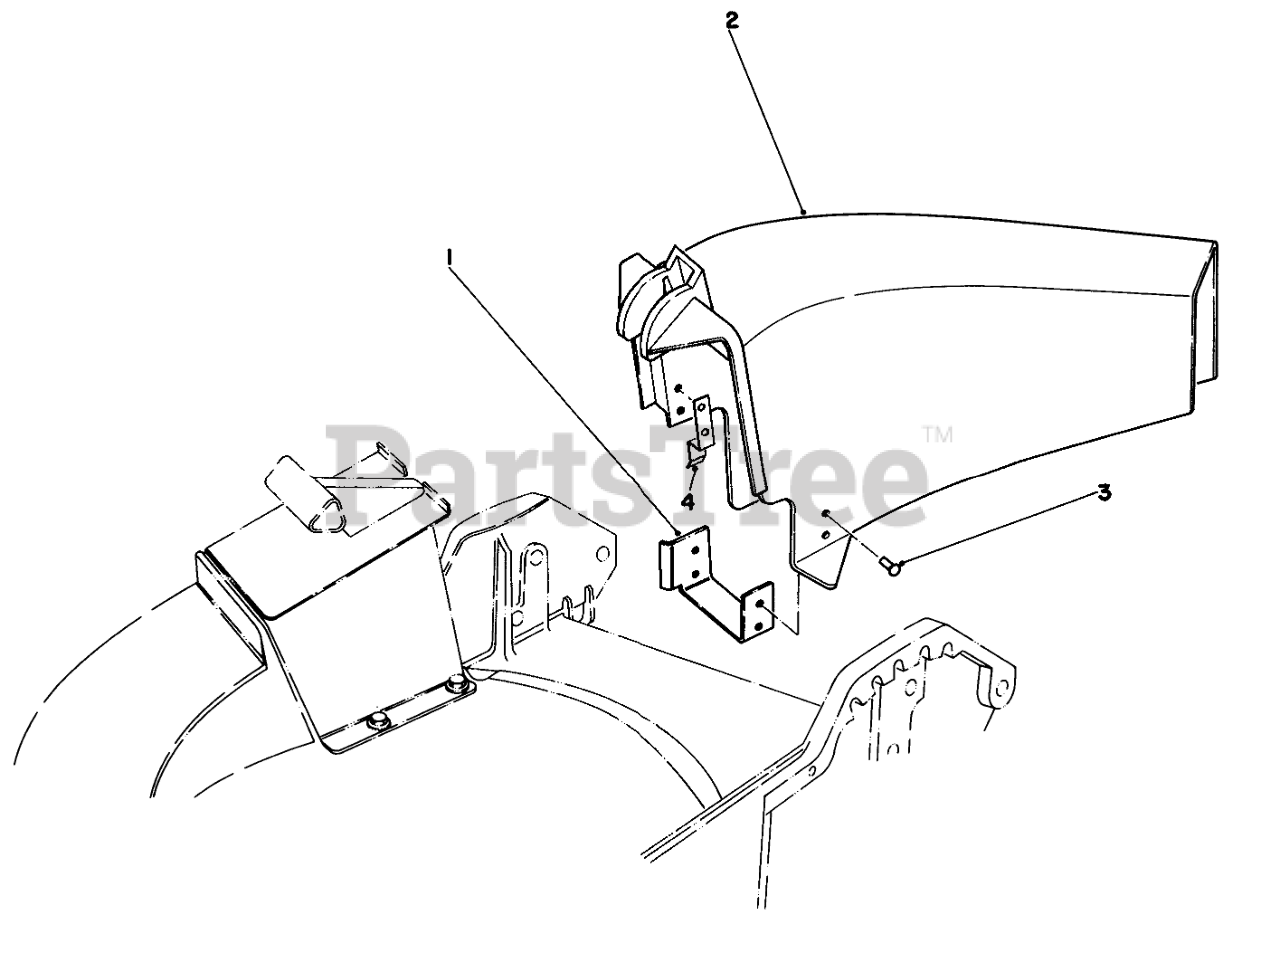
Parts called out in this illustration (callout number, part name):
1	CHUTE BRACKET
2	Chute Discharae
3	RIVET
4	CHUTE TAB
